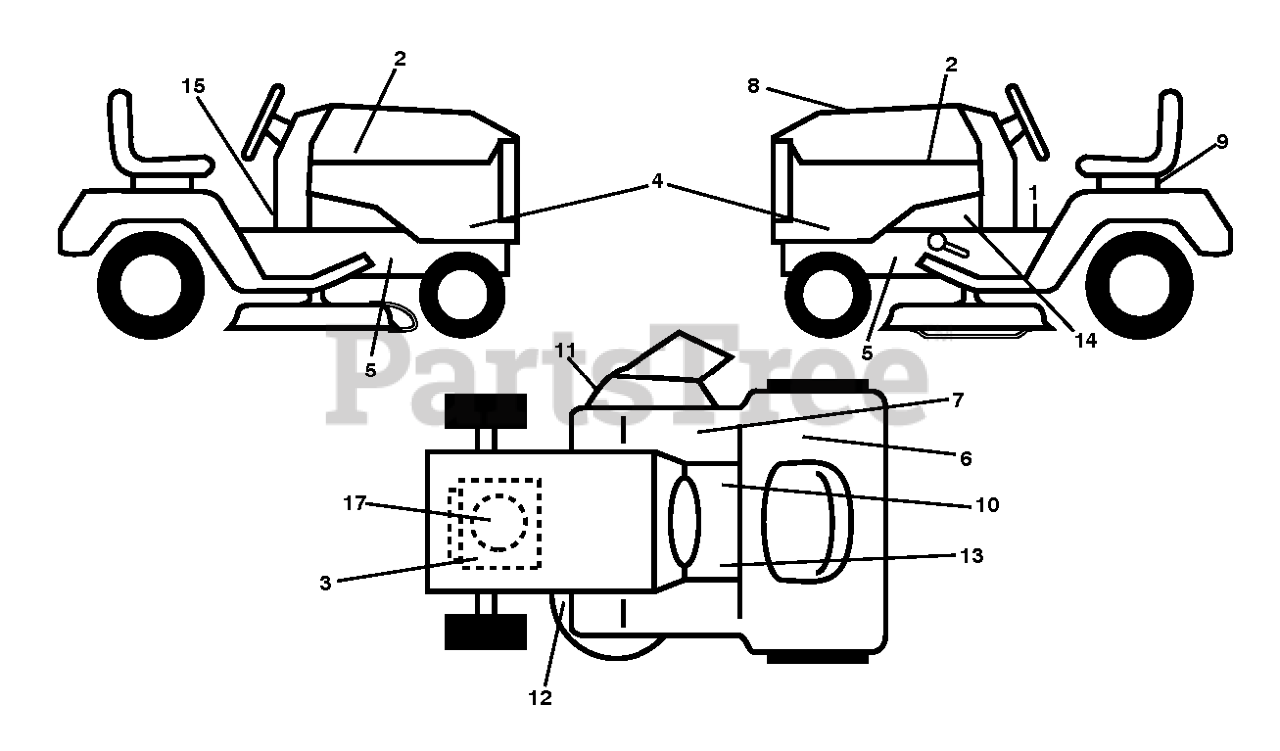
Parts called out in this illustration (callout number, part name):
1	LABEL
2	RP.DECAL.BADGE.170MM.TEXTLOGO
3	DECAL
6	Decal, Fender 100 DB/CE
7	DECAL
8	DECAL DECAL.RPL.BSM21.PB.TLW.3
9	DECAL BTRY SYMBOLS
10	DECAL PARK BRAKE
11	DECAL, WARN. DEFLECT/CTFGR
12	Decal, Mower V-Belt Schematic
13	DECAL
17	DECAL
